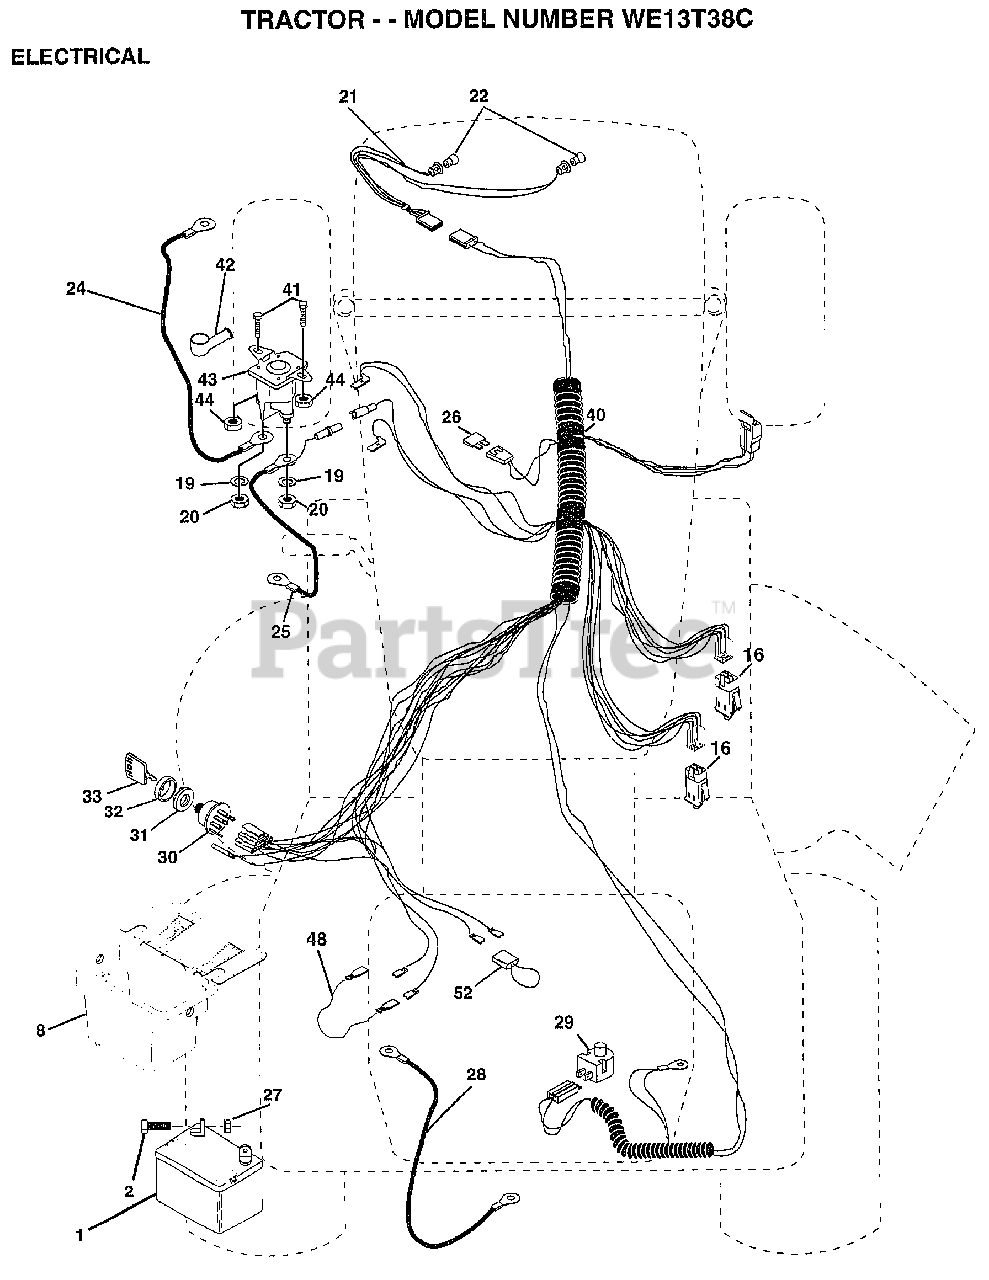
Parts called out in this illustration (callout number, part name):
2	BOLT LT
8	"CASE,BATTERY.MECH"
16	SWITCH INTERLOCK
20	NUT
21	HARNESS.ASM.LIGHT W/4152J
22	HEADLAMP BULB
24	CABLE ASM.
25	CABLE.BTRY.6GA.RD
26	FUSE.15 AMP
27	NUT
28	CABLE T
29	SWITCH SEAT
30	SWITCH IGN 4POS
31	NUT IGNITION
32	COVER KEY SWITCH
33	KEY
40	HARNESS.IGNITION
41	BOLT HXHD FIN
44	NUT HXKEP 1/4X20
48	ADAPTER AMMETER
52	PROTECTION LOOP
